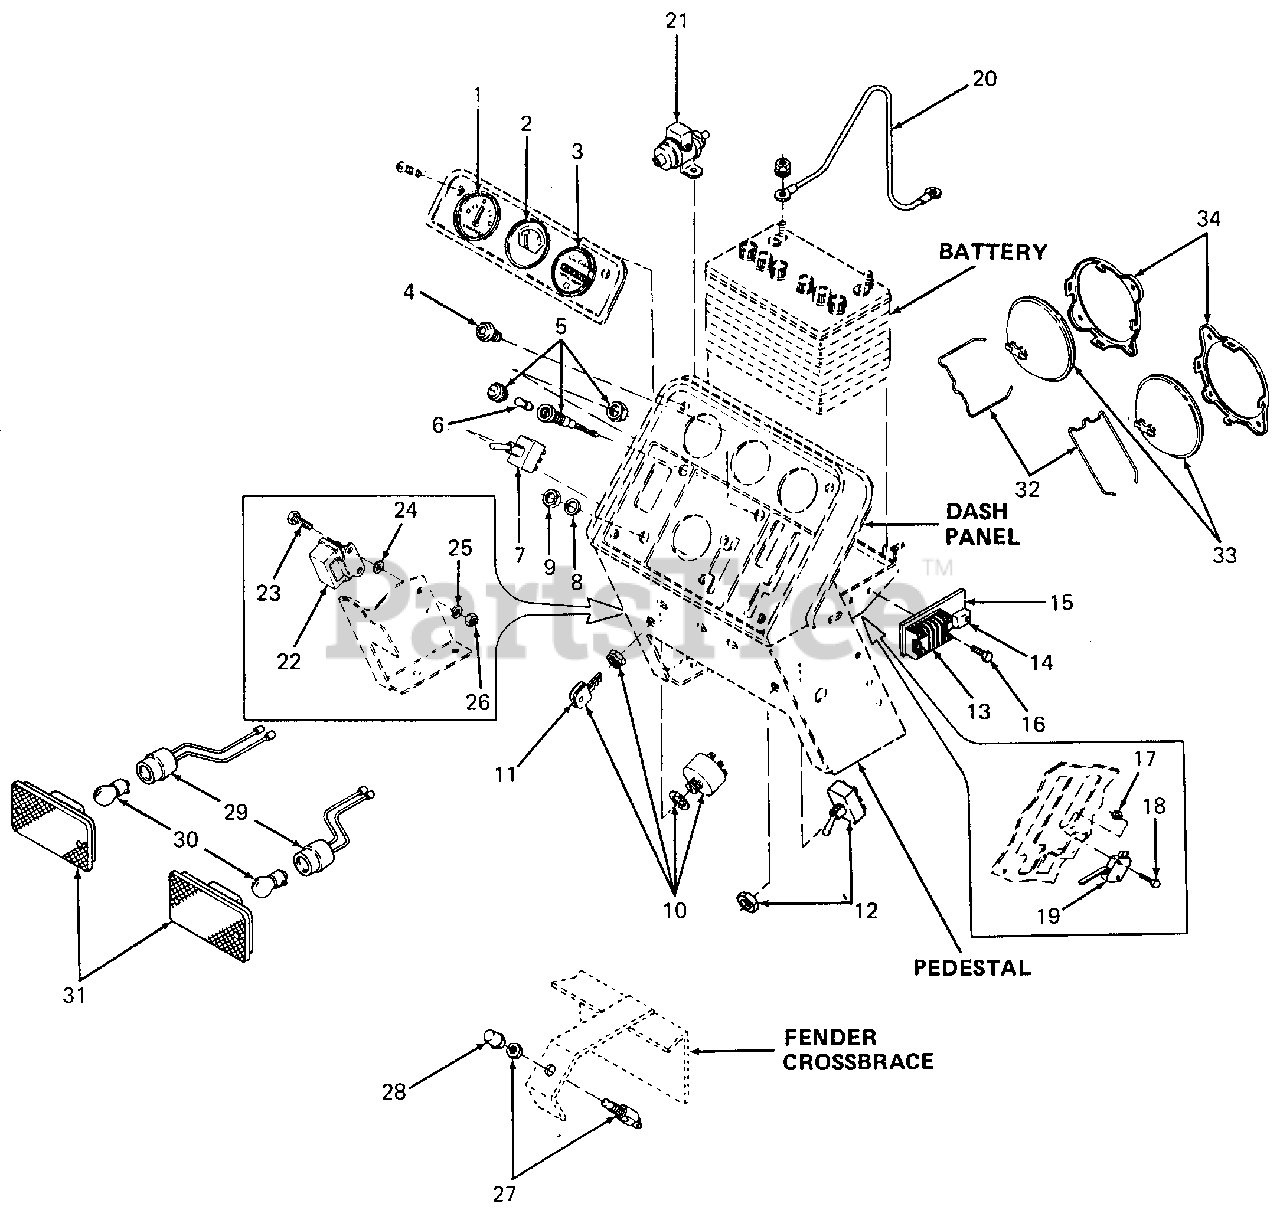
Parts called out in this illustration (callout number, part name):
1	Ammeter
2	Gauge, Water Temperature
3	Hourmeter
4	Indicator, Glow Plug
5	Light Assy, Oil Indicator
6	Bulb, Light
7	Switch, PTO
8	Washer, Flat, .531 X .680 X .054 Thk
9	Nut, Hex, 1/2-27 X 1.00 Thk
10	Switch, Key
11	Key, Ignition (Set of 2)
12	Light Switch w/Nut
13	Regulator
14	Circuit Breaker
15	Bracket, Circuit Breaker
16	Screw, Hex Cap, 1/4-20 X 1.50 Lg
17	Nut, Hex Insert Lock, #4-40
18	Screw, Hex Mach, #4-40 X .75 Lg
19	Switch, Reverse
20	Wire, Electric, 14.0 Lg - Black
21	Pump, Electric Fuel
22	Relay
23	Screw, Hex Cap, 1/4-20 X .62 Lg GR5
24	Washer, External Lock, 1/4
25	Washer, Lock, 1/4
26	Nut, Hex, 1/4-20 GR5
27	Switch w/Nut
28	Boot, Switch
29	Cable Assy, Tail Light
30	Bulb, Light
31	Lens Assy, Tail Light
32	Spring, Headlight Retaining
33	Headlight
34	Retainer, Headlight
